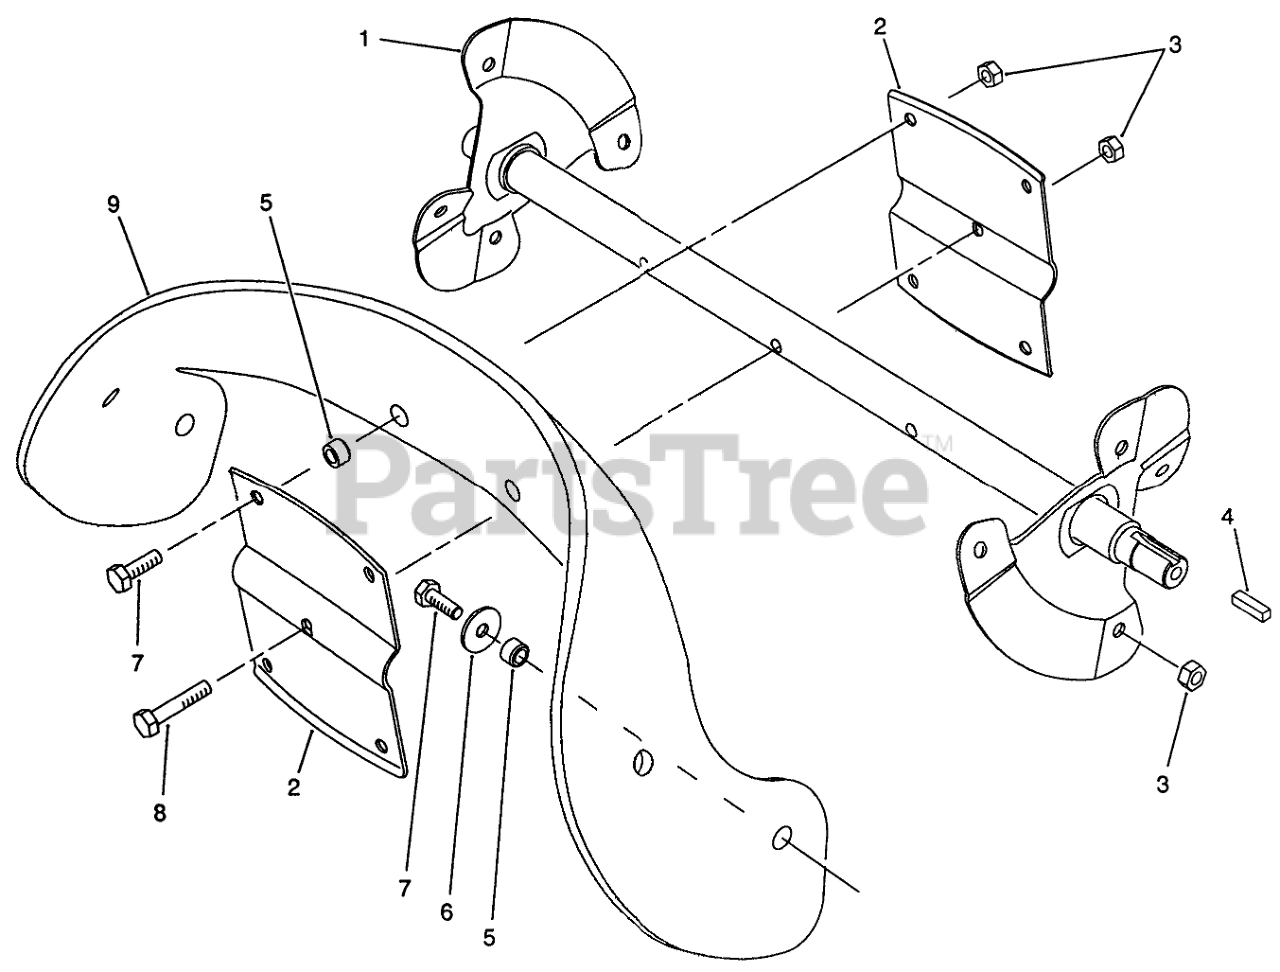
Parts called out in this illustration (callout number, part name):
1	Rotor Shaft Assembly
2	Rotor
3	NUT-LOCK, NI
4	KEY-SQUARE
5	SPACER-BLADE, ROTOR
6	WASHER-FLAT
7	SCREW-HH
8	SCREW-HH
9	Blade-Rotor
